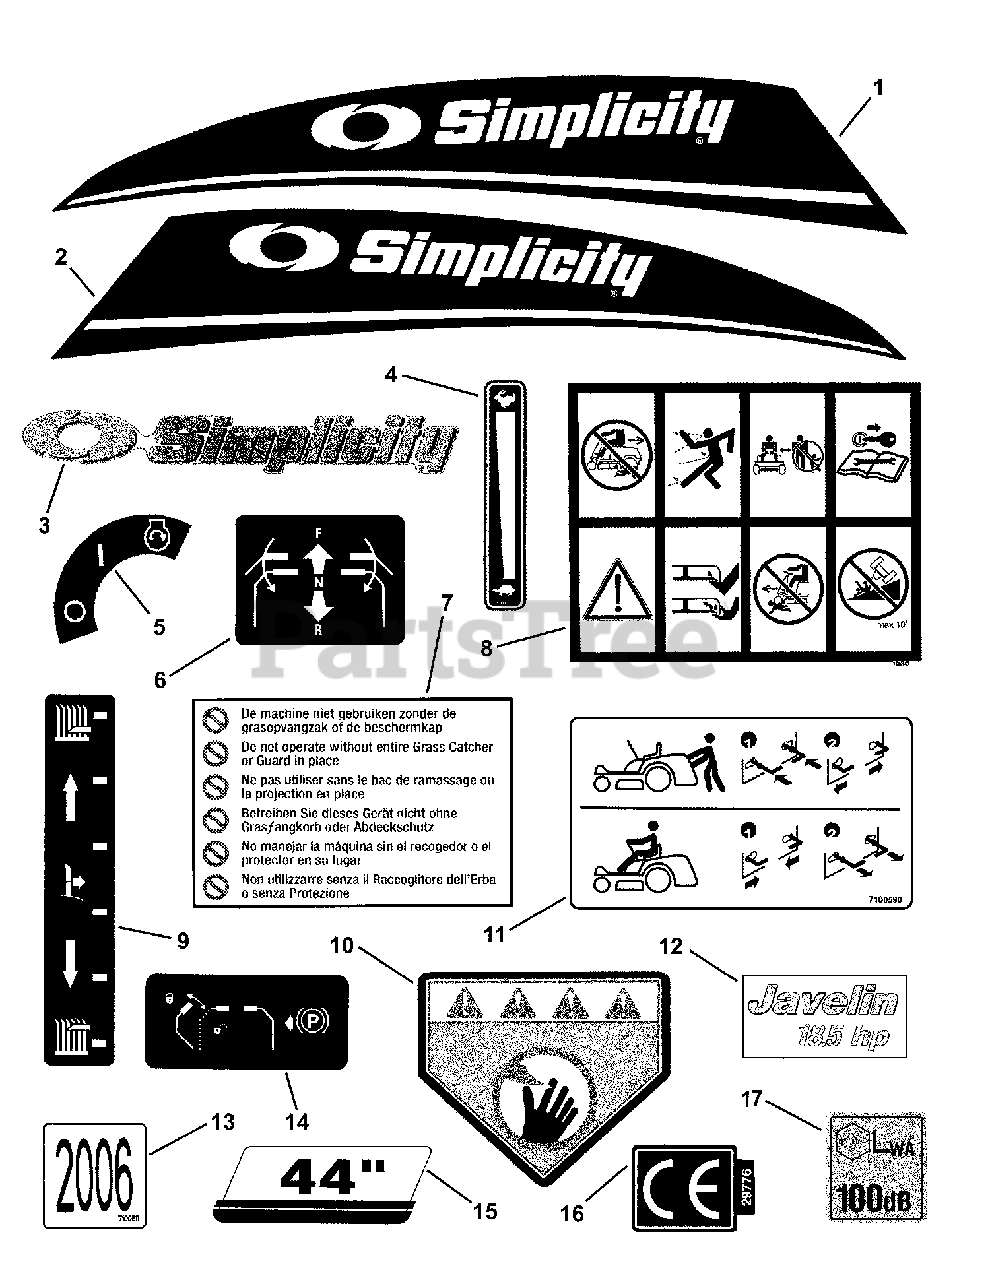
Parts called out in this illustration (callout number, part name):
1	DECAL, Simplicity Fender, LH
2	DECAL, Simplicity Fender, RH
3	DECAL, Simplicity Logo GV3079178
4	DECAL, Throttle Control, RZT
5	DECAL, Ignition, RZT
6	DECAL, Motion Control, Symbols, ERZT
7	DECAL, Deck / Chute INT'L Warning
8	DECAL, Safety Symbols, RZT
9	DECAL, Height Of Cut, Symbols, ERZT
10	DECAL, Warning
11	DECAL, Roll Release, ERZT
12	DECAL, Javelin, 18.5 HP
13	DECAL, 2006 Year Of Mfg.
14	DECAL, Park Brake, ERZT
15	DECAL, 44", Silver On Black w/Stripe
16	DECAL, Euro Community, CE
17	DECAL, Sound, 100
